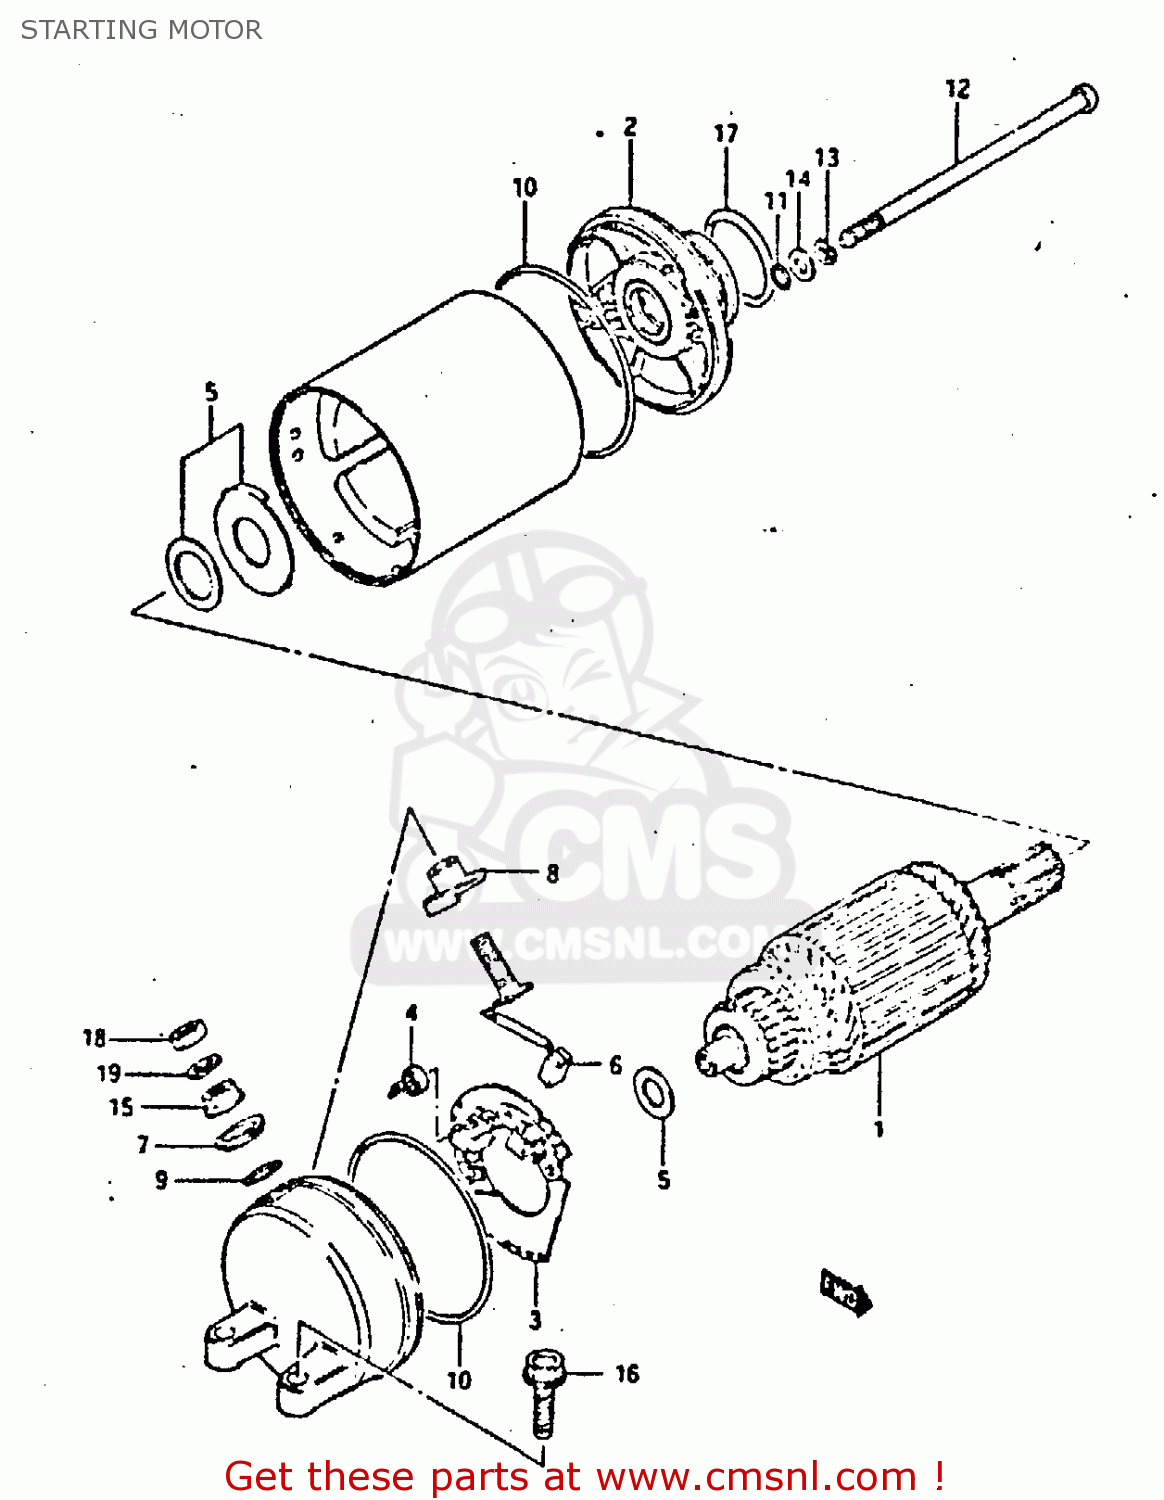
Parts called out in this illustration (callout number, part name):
1	ARMATURE
2	BRACKET SET
3	HOLDER,BRUSH
4	SPRING
6	BRUSH SUB ASSY,STARTING MOTOR
7	BUSHING
8	BUSH,B
9	O RING
10	O RING
11	O RING
12	BOLT
13	WASHER,LOCK
14	WASHER
15	NUT 6MM
16	BOLT(6X23)
17	O RING(D:3,ID:24.5)
18	NUT
19	WASHER,LOCK
